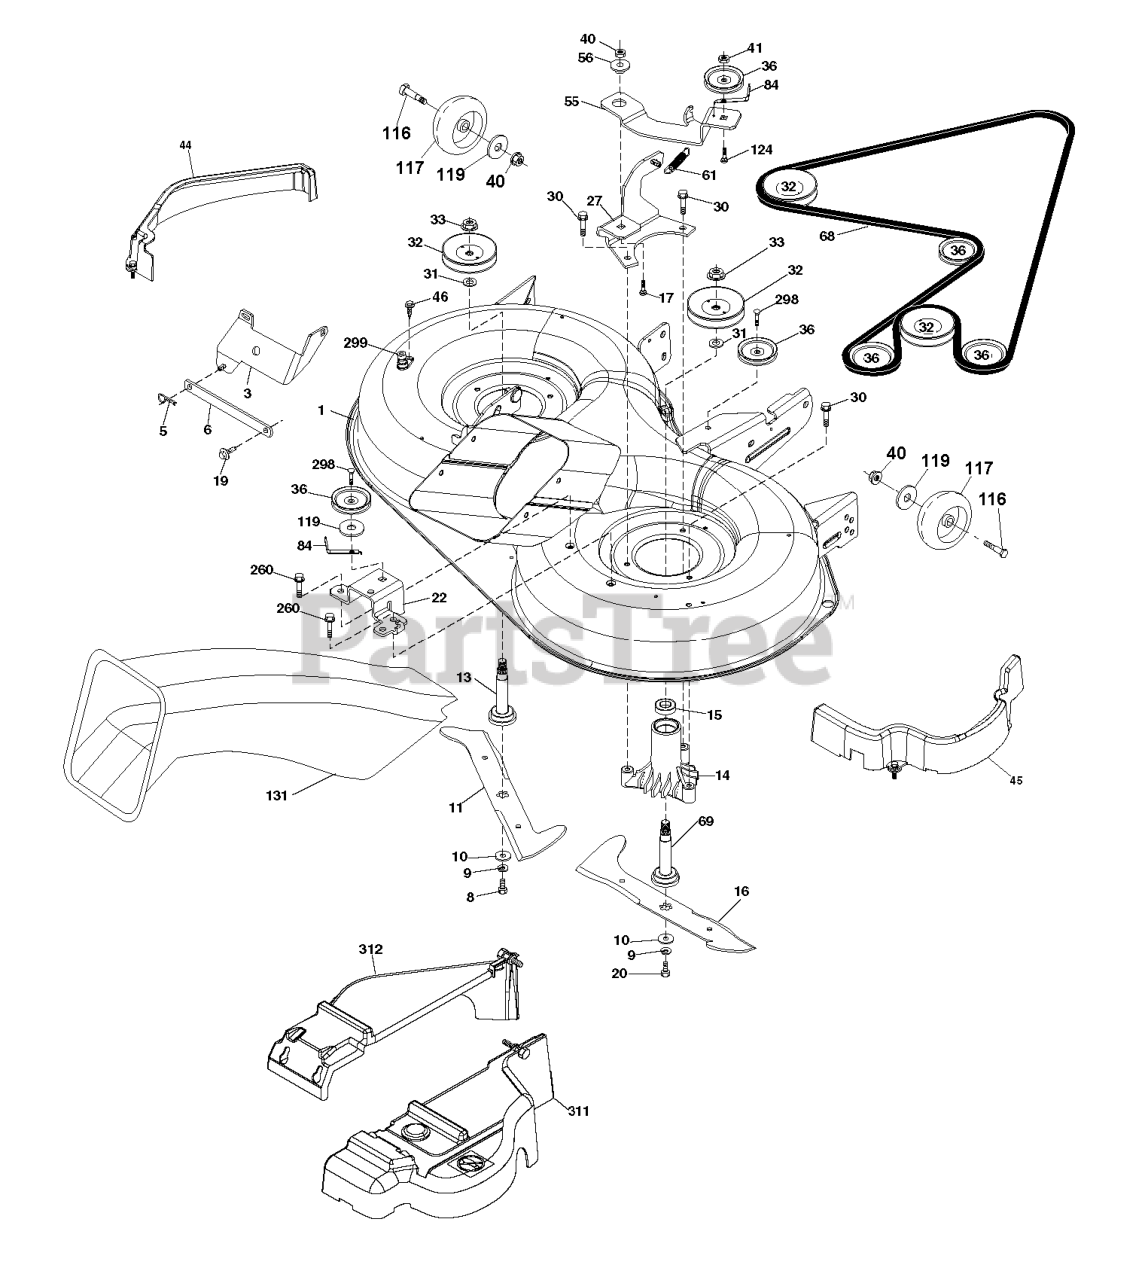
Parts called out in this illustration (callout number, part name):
1	DECK.WLDT.97.CRD.2GWB.
3	BRACKET.ASM.BAR.SWAY.CHASS
5	RETAINER-SPRNG RB
6	BAR.SWAY.92.CRD
8	BOLT.3/8-24X1.25 GR8
9	LOCKWASHER
10	WASHER.BLADE
11	BLADE.3N1.LH.CRD.97
13	SHAFT ASM VENT
14	HOUSING.MANDREL.VENTED (MACHD)
16	BLADE.3N1.RH.CRD.97
17	BOLT.3/8-14X1.25
19	BOLT SHD 5/16-18
20	BOLT.3/8-24X1.25GR8. LHTHRD
22	BRACKET.SUPT.IDLER.REAR.RH
27	BRACKET.ASM.SUSP.REAR.RH.
30	SCREW, WASHER HEAD
31	WASHER.SPACER.MANDREL
32	PULLEY MANDREL
33	NUT.FLANGE.LOCK.TOP
36	PULLEY.IDLER.4.25
41	NUT LOCK FLG 3/8-16 UNC
44	COVER MANDREL LEFT
45	COVER MANDREL RIGHT
46	SCREW.1/4-20X5/8
55	ARM.IDLER.92 CRD.2006
56	SPACER.RETAINER.MOWER
61	SPRING
68	BELT.DRIVE.CRD.97.2010
69	SHAFT.ASM.W/LWR.BRG.RH.THREAD
84	KEEPER, BELT IDLER
116	BOLT.SHOULDER.3/8-16X3-5/8.
117	RP WHEEL. GUAGE RALLY
119	WASHER
124	BOLT.3/8-16X1.50
131	CHUTE BAGGER
260	SCREW 3/8-16X1/2
298	SCREW LT
299	PORT.WASHOUT
311	COVER RIGHT
312	COVER LEFT
